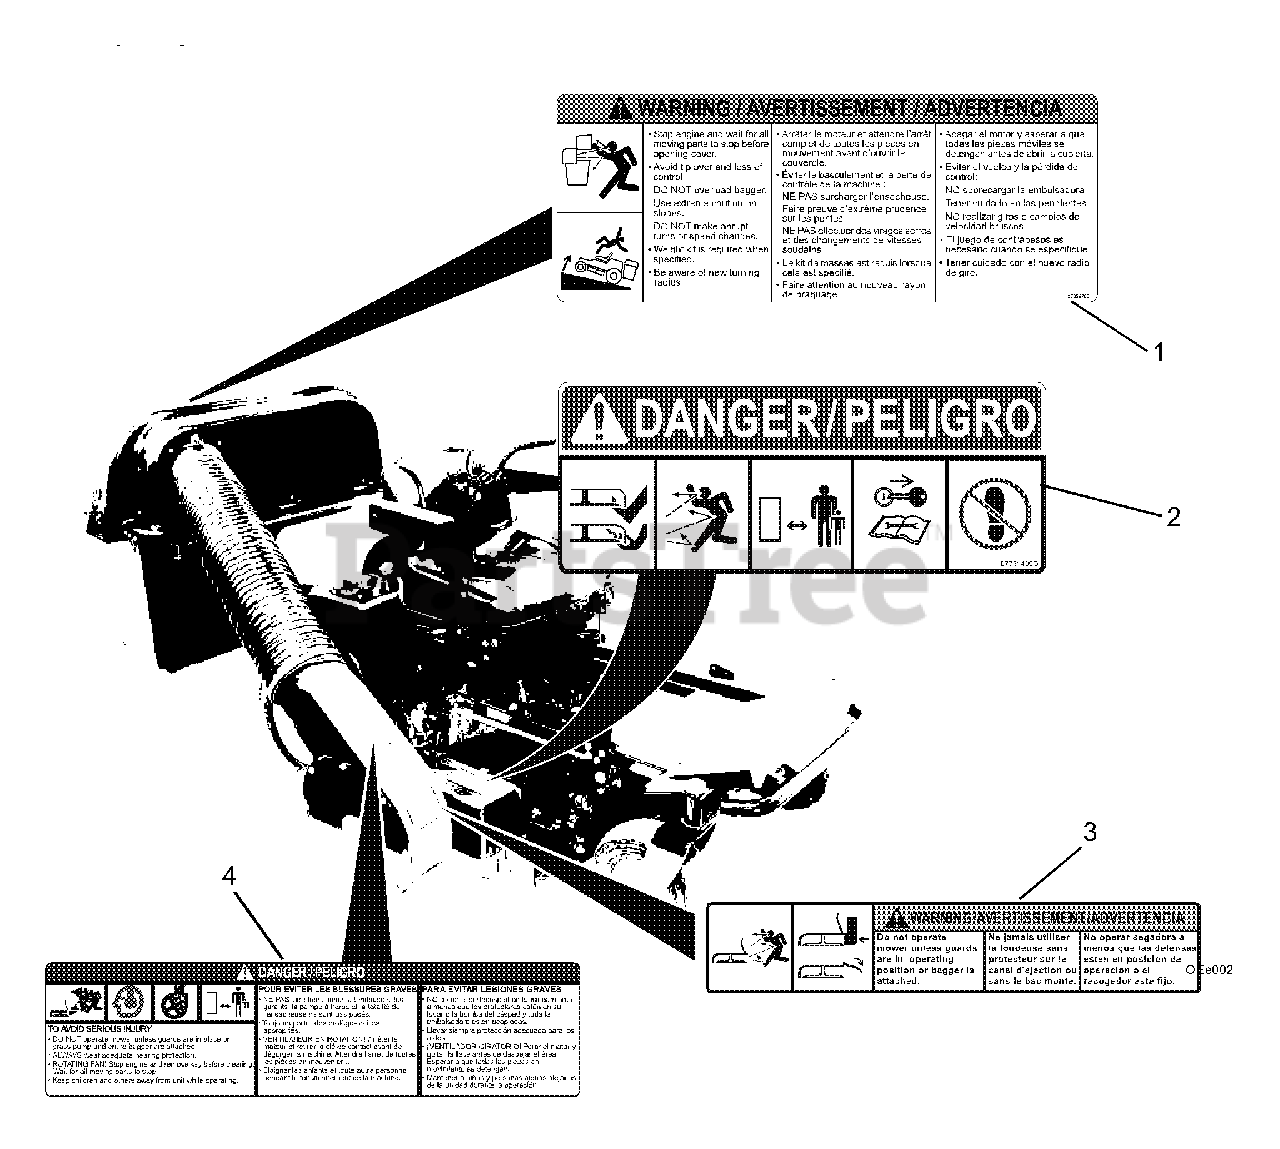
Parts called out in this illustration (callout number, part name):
1	Bagger Cover Decal
2	Mower Pan Danger Decal
3	Warning Decal
4	Grass Pump Caution Decal
